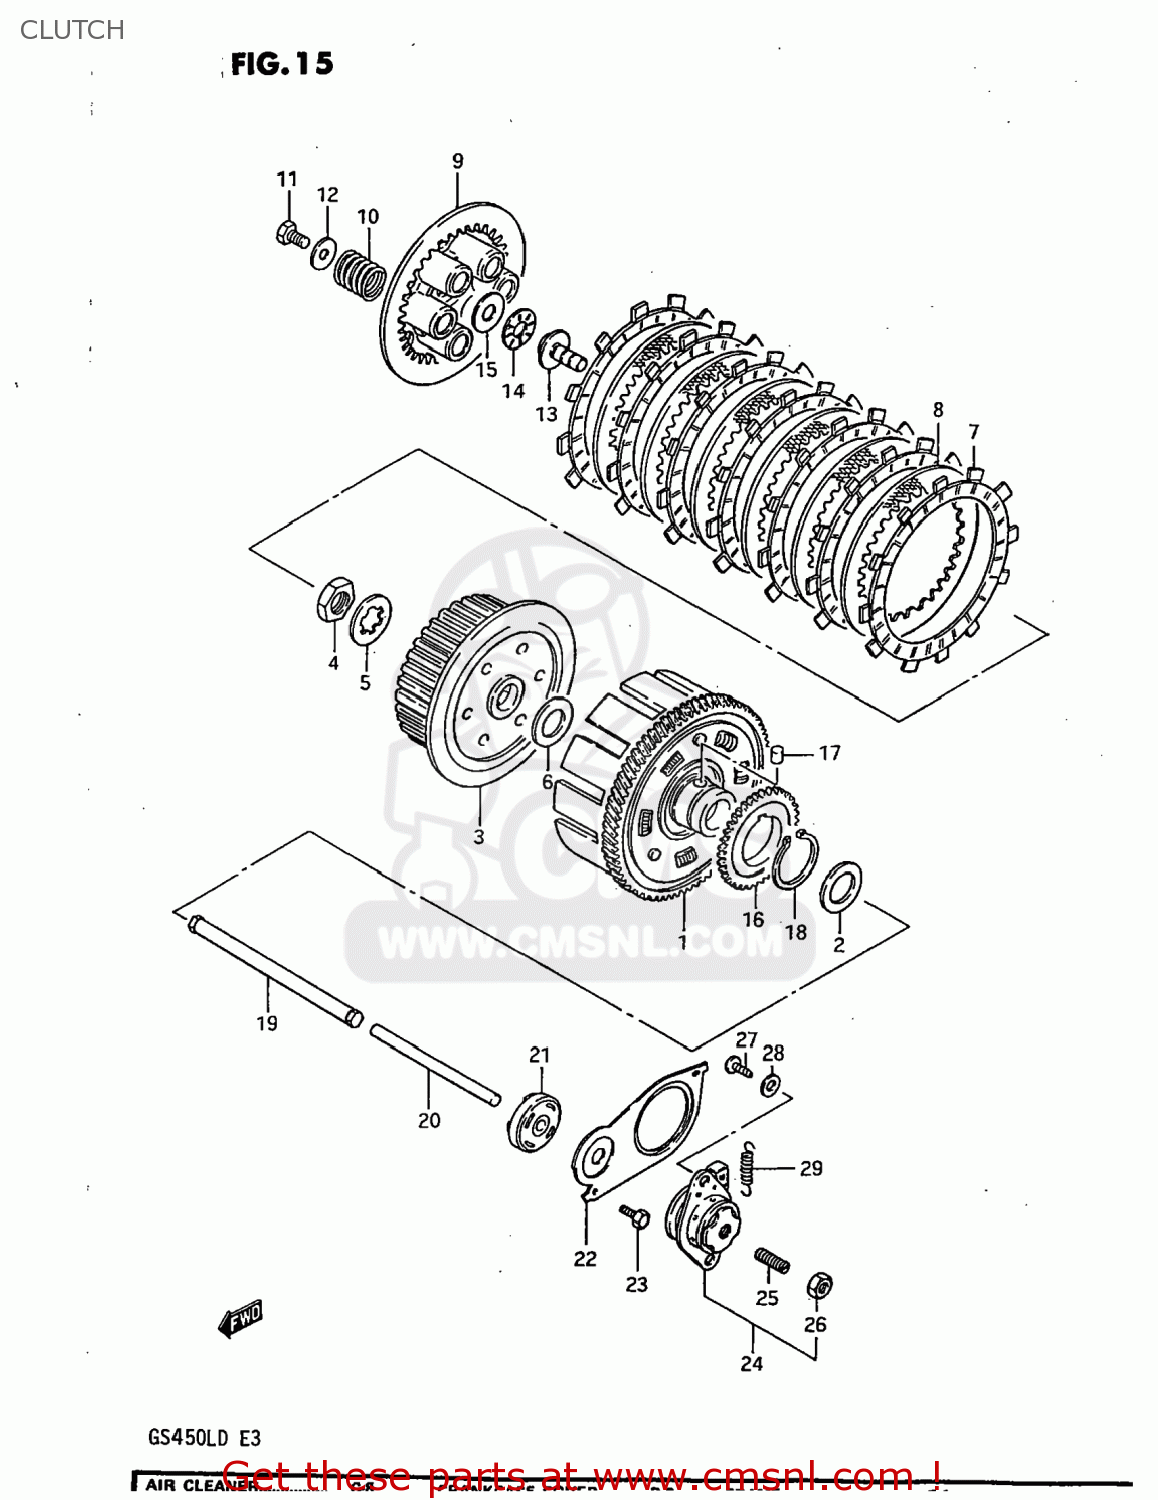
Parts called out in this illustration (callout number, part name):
1	GEAR ASSEMBLY,PRIMARY DRIVE
2	WASHER
3	HUB,CLUTCH SLEEVE
4	NUT (20MM)
5	WASHER,LOCK
6	WASHER(20X44X3)
7	PLATE,CLUTCH DRIVE (MCA)
8	PLATE,CLUTCH DRIVEN (NAS)
9	DISC,CLUTCH PRESSURE
10	SPRING
11	BOLT, UPPER
12	WASHER
13	PIECE,CLUTCH PUSH
14	BEARING(15X28X2)
15	WASHER
16	GEAR,OIL PUMP DRIVE
17	PIN(6X6)
18	CIRCLIP
19	ROD,CLUTCH PUSH
20	ROD,CLUTCH PUSH
21	SEAL,OIL(6X34X10)
22	PLATE,CLUTCH PUSH ROD
23	BOLT
24	SCREW ASSY,CLUTCH RELEASE
25	SCREW
26	NUT 6MM
27	SCREW
28	WASHER
29	SPRING
